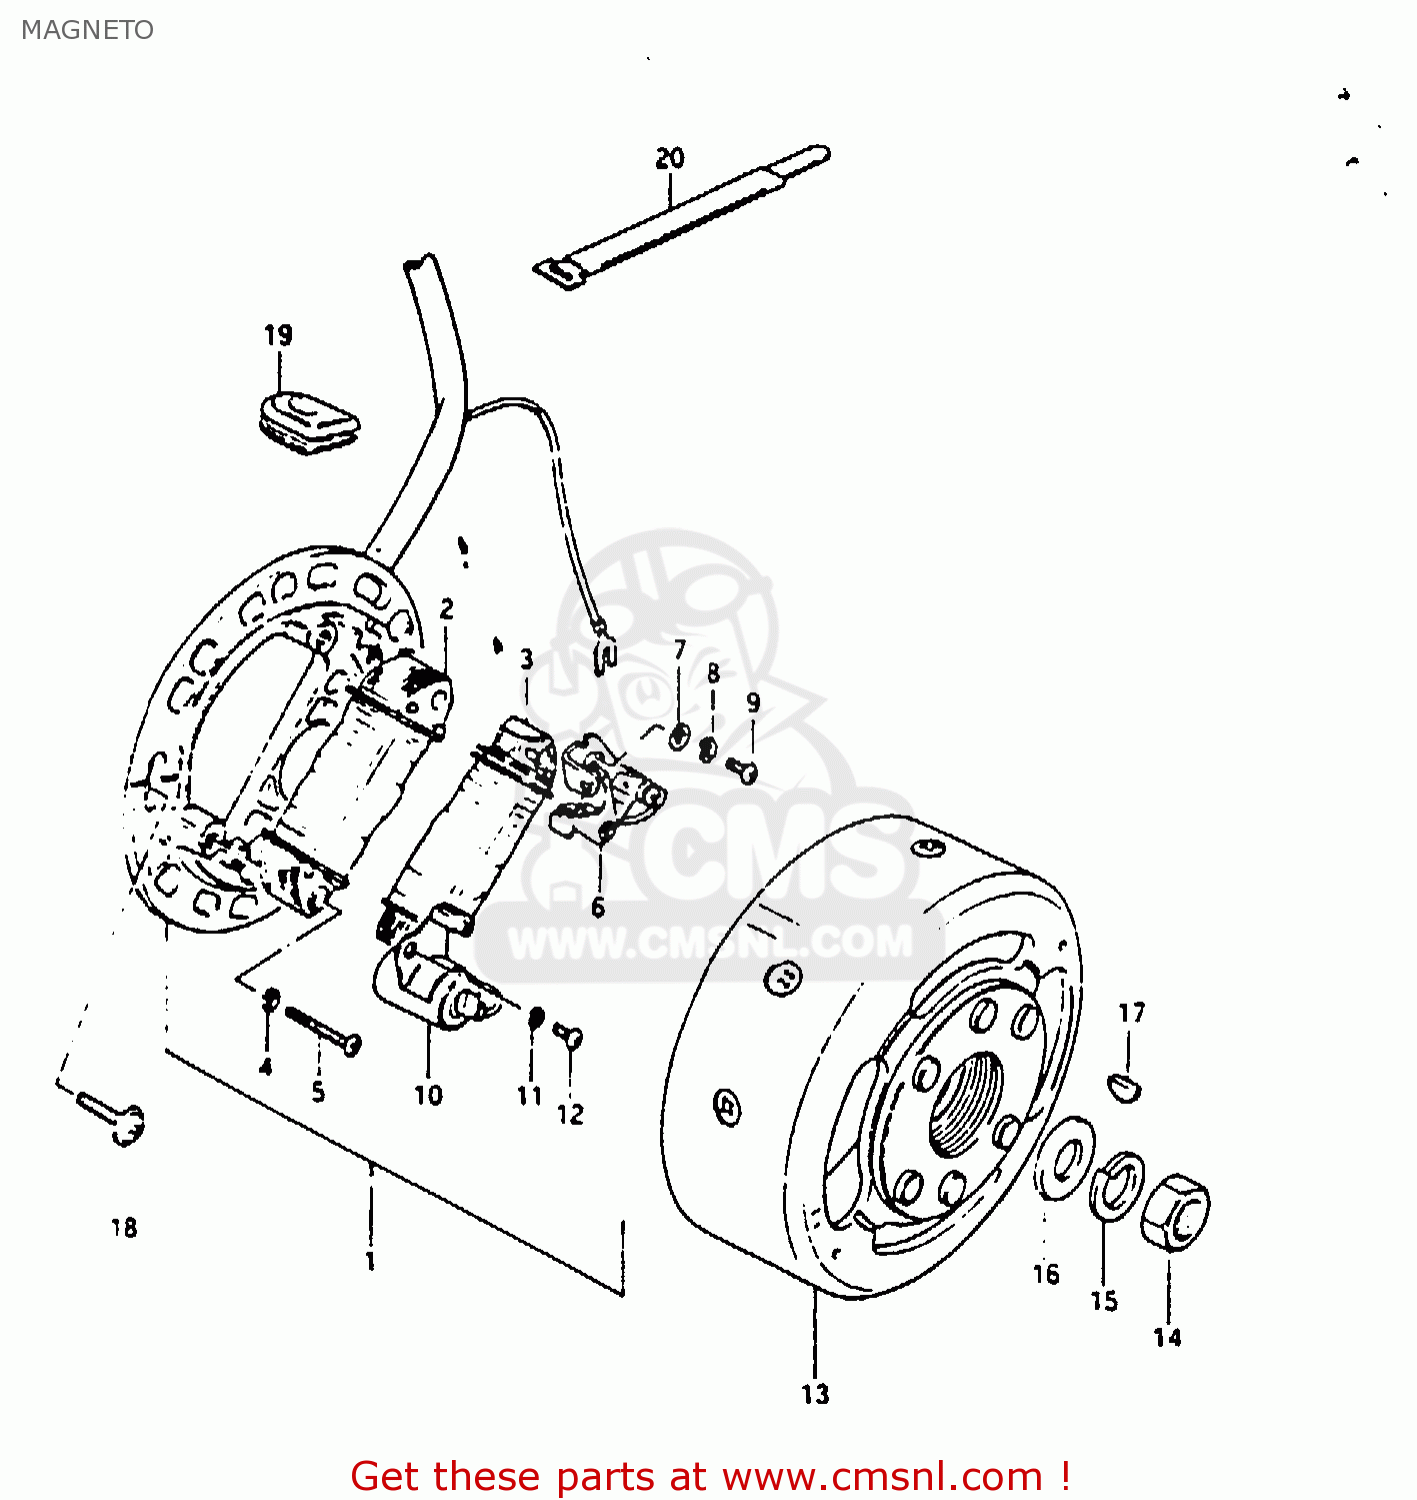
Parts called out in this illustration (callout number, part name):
1	STATOR ASSY
2	COIL, LIGHTING
3	COIL,PRIMARY
4	WASHER,LOCK 4M
5	SCREW
6	POINT ASSY,CONTACT
7	WASHER 4MM
8	WASHER,LOCK 4M
9	SCREW(4X10)
10	CONDENSER
11	WASHER,LOCK 4M
12	SCREW
13	ROTOR, FLYWHEEL
14	NUT (10MM)
15	WASHER,LOCK,10
16	WASHER
17	KEY
18	SCREW
19	GROMMET
20	CLAMP
